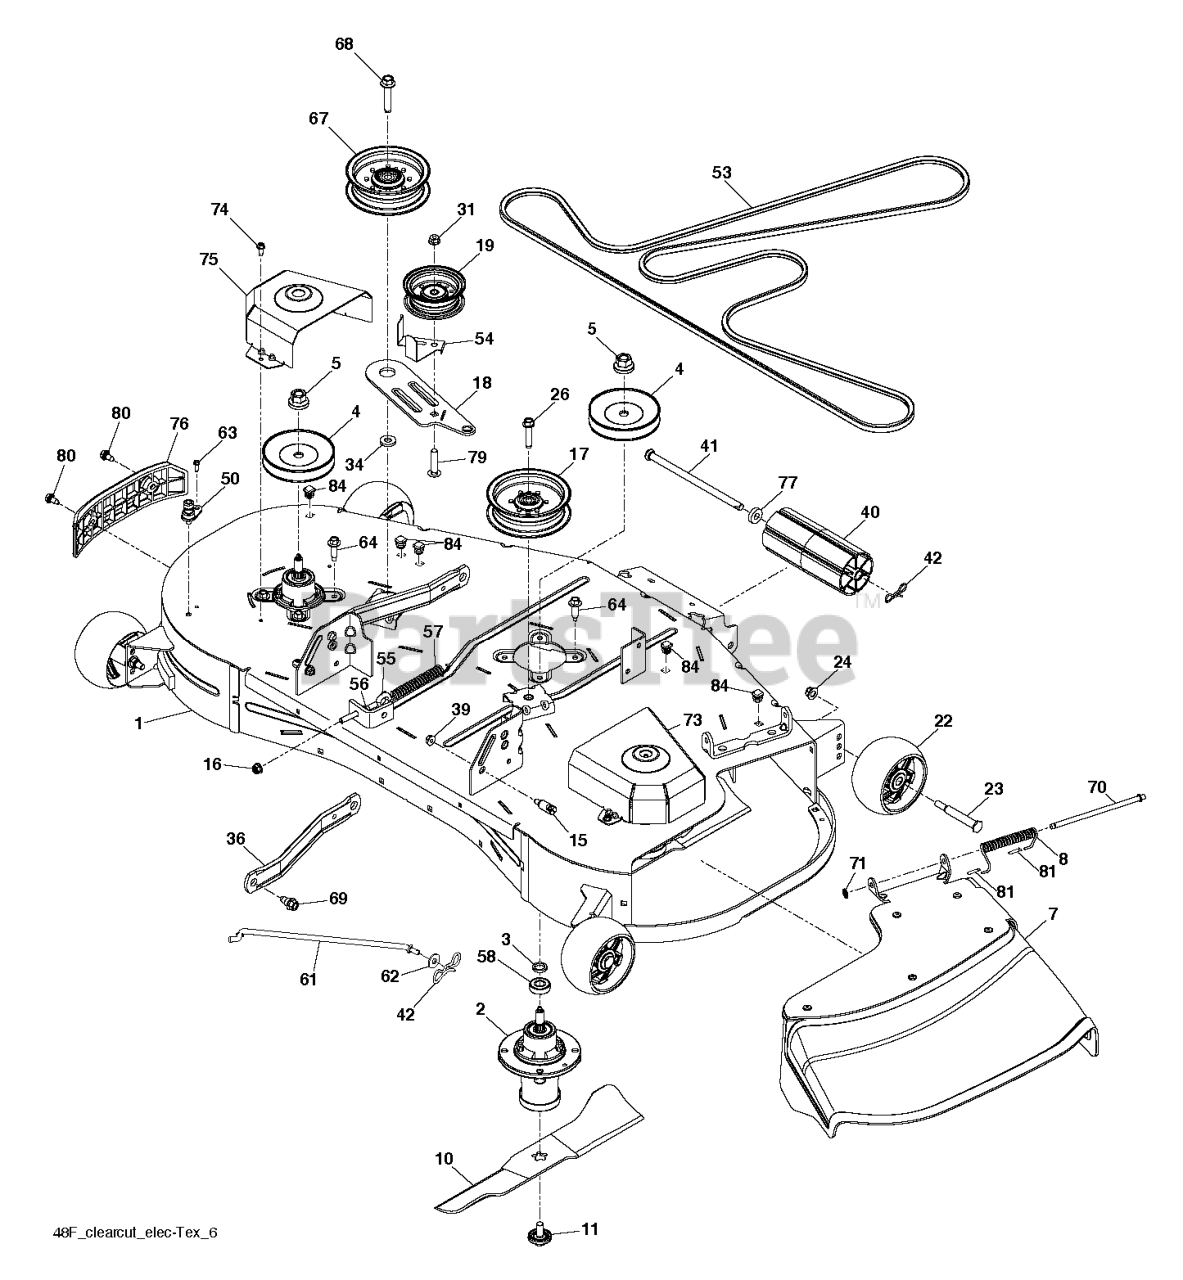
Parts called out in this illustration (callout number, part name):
1	DECK.SVC.48.CC.ASM.668
2	MANDREL ASM, CAST IRON
3	WASHER.SPACER.MANDREL
4	MANDREL PULLEY
7	GSPW Deflectors
8	SPRING.42.FCS.DEFLECTOR
10	BLADE.BAGGER.RES.CLRCT.48".BLK
11	BOLT.WASHER.ASM.7/16-2
15	STUD.FASTNER.W/ANTI-ROTATE
16	5/16-18 NYLOC FLANGE NUT
17	PULLEY.IDLER.MWR.STATI.LH
18	ARM.PNT.CLUTCHING.EDIP
19	PULLEY.IDLER.48"PRIMARY
22	WHEEL.GAUGE.RALLY
26	SCREW.7/16-14 X 2.125.WASHER
31	NUT LOCK FLG 3/8-16 UNC
36	ARM.RFIXED.MOWER.SUSPNSIONX431
40	NOSE ROLLER 48"
42	PIN.COTTER.5/16.BOW TI
50	PORT.WASHOUT
53	BELT.DECK.TRACTOR
54	GUARD, BELT
55	GSPW Bolts
56	GSPW Hardware
57	SPRING.EXTN.42.FCS.TR.DECK.DRV
63	SCR 1/4-20X5/8 HEX SELF TAP ZD
64	BOLT.HEX.WASHR.HED.313-18X1.19
67	PULLEY.IDLER.2006
68	BOLT;HEX_3/8-16 X 1.78.CLRZINC
69	BOLT.SHOULDER
71	NUT PUSH M
73	COVER.PNT.MANDREL.RH.GREY
74	SCREW.1/4-20X5/8
75	COVER.PNT.MANDREL.LH.TR.GREY
76	BUMPER 48 CLEARCUT TRIM SIDE A
77	BUSHING.NOSE.ROLLER
80	SHOULDER BOLT 5/16-18TT
81	CAP-SLEEVE LT
